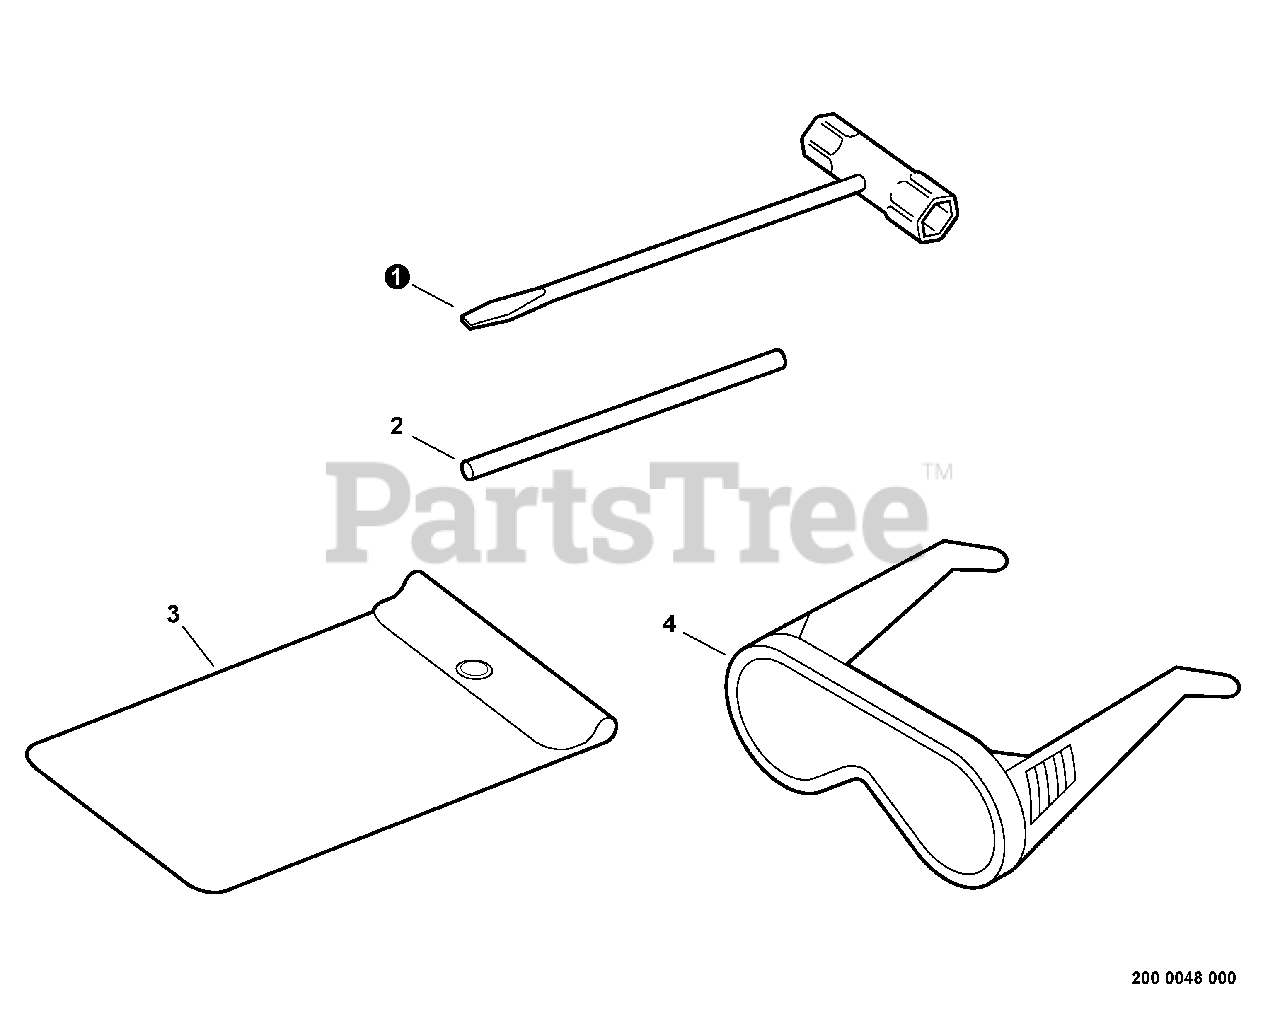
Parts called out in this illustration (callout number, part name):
1	T-WRENCH 17x-19 L200
2	TOOL, LOCKING 5×120 MM
3	BAG, TOOL
4	GLASSES, SAFETY
